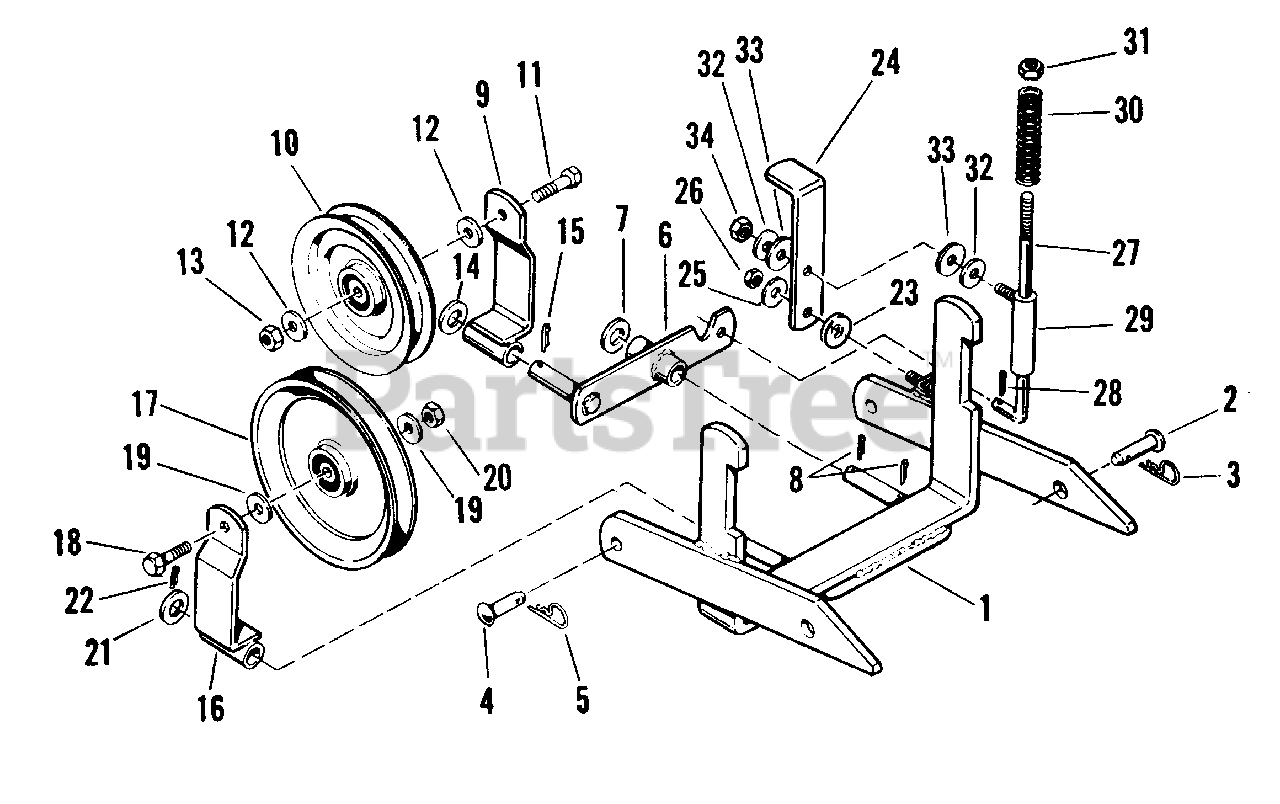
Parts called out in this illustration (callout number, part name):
1	Hitch Assembly
3	Spring Clip
5	Spring Clip
6	Idler Lever Assembly
8	Cotter Pin, 1/8" x 1"
9	Idler Bracket
10	Idler Pulley
11	Hex Capscrew, 3/8"-16 x 1-1/4"
12	Plain Washer, 5/16"
13	Hex Nut, Full, Lock, 3/8"-16
15	Cotter Pin, 1/8" x 1"
16	Idler Bracket
17	Idler Pulley
18	Hex Capscrew, 3/8"-16 x 1-1/2"
19	Plain Washer, 5/16"
20	Hex Nut, Full, Lock, 3/8"-16
22	Cotter Pin, 1/8" x 1"
23	Washer, Nylon
26	Hex Nut, Full, Lock, 5/16"-18
28	Cotter Pin, 3/32" x 3/4"
29	Rod Guide Assembly
31	Hex Nut, Full, Lock, 5/16"-18
32	Plain Washer, 1/4"
33	Washer, Nylon
34	Hex Nut, Full, Lock, 5/16"-18
